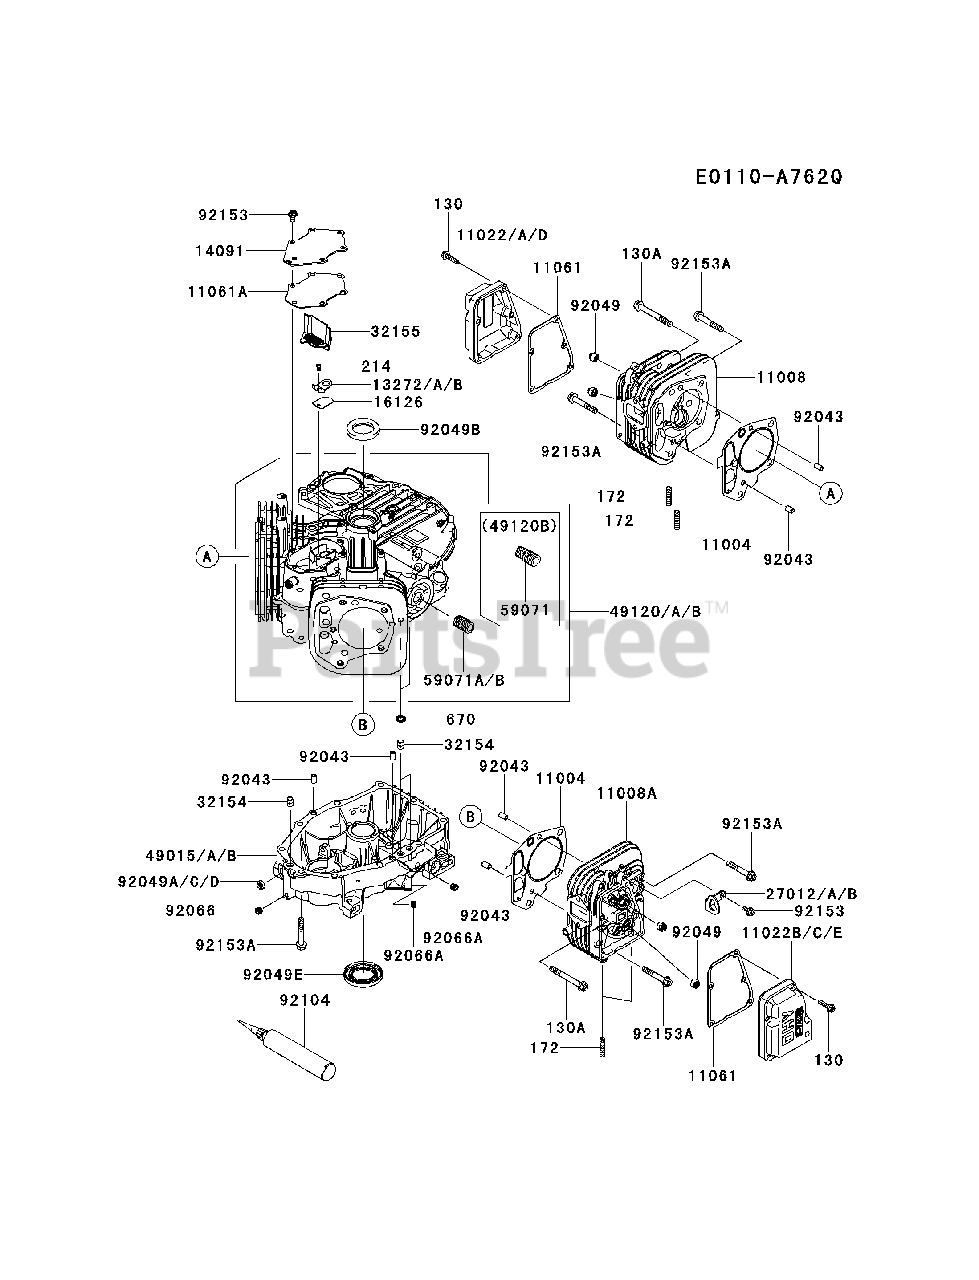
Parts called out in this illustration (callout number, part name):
130	BOLT-FLANGED,6X25
130A	BOLT-FLANGED,8X70
172	BOLT-STUD,8X18
214	SCREW-PAN+-,4X8
670	O RING,11MM
92153A	BOLT,8X50
